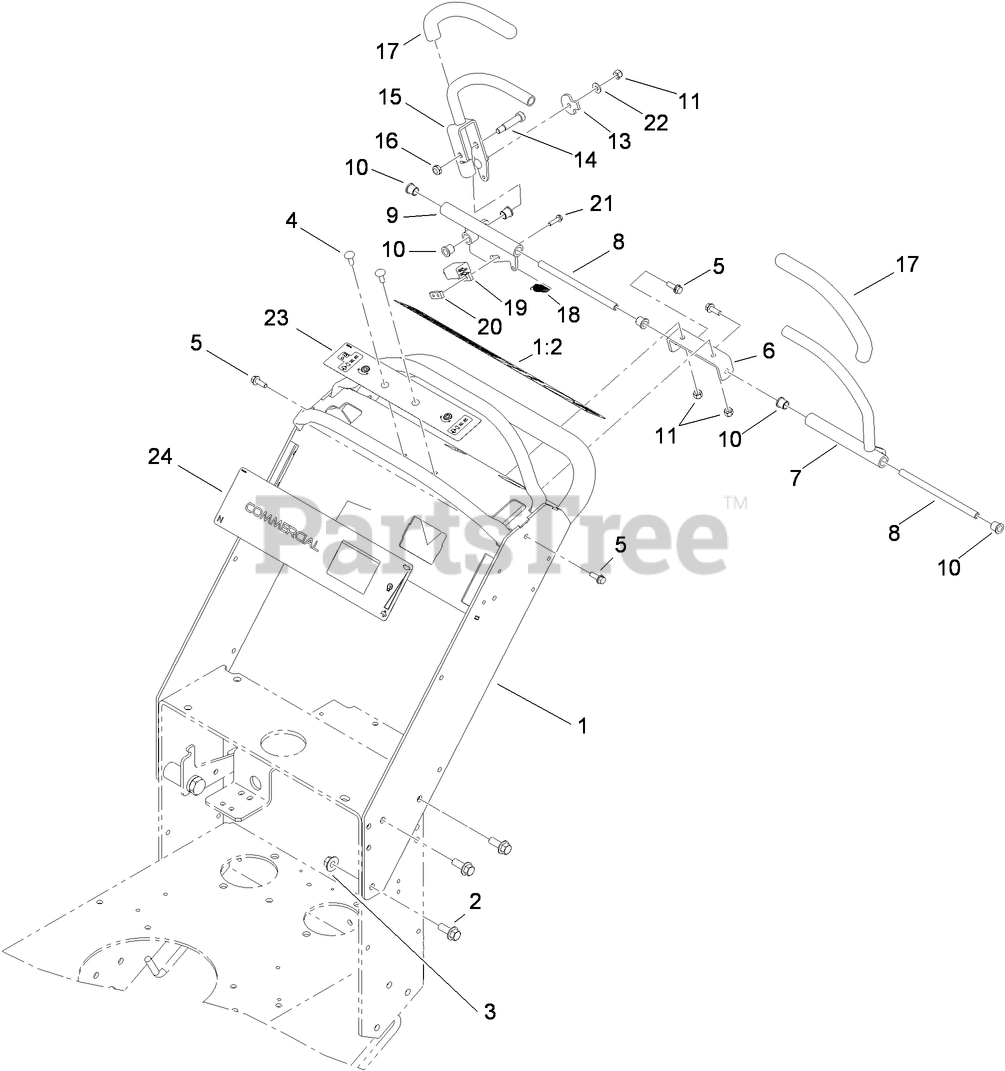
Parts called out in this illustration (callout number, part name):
1	T-BAR HANDLE ASM
1:2	DECAL-WARNING, CONTROL
2	SCREW-HHF
3	NUT-FLANGE
4	BOLT-CARR
5	SCREW-HHF
6	BRACKET-SUPPORT
7	LEVER-CONTROL
8	SHAFT-PIVOT
9	MOTION CONTROL ASM
10	BEARING
11	NUT-LOCK, NI
13	CAM-LEVER
14	SCREW-HSH
16	NUT-LOCK, NI
17	GRIP-LEVER
18	SPRING-EXTENSION
19	SWITCH-CLOSED, NORMALLY
20	PLATE-TAPPED
21	SCREW-HWH
22	WASHER-FLAT
23	DECAL-CONTROL
24	DECAL-PANEL, CONTROL
